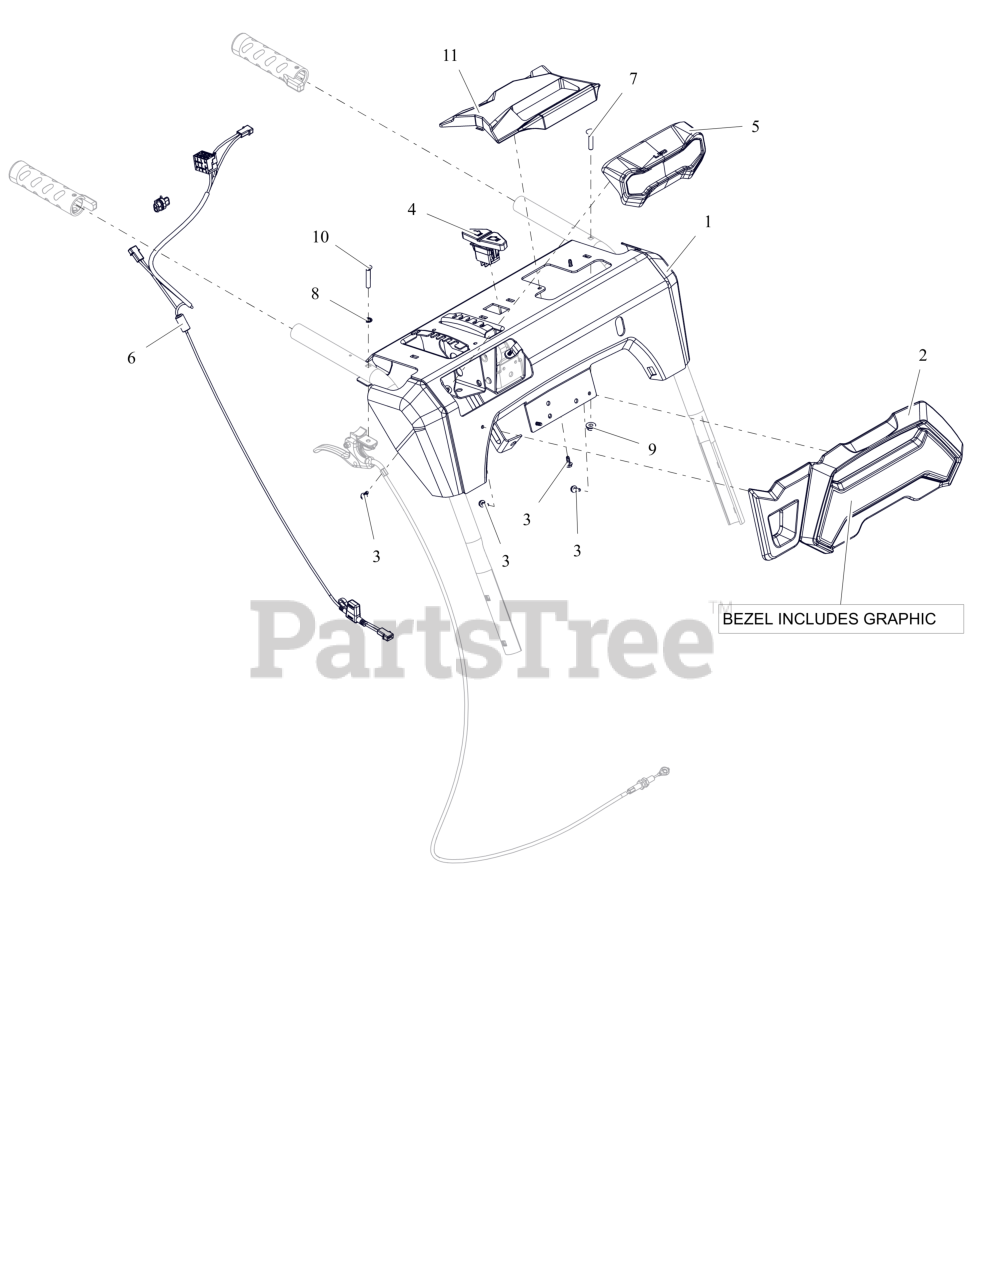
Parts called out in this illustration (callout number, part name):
1	PANEL, CONTROL-EFI ID W/DECAL
2	BEZEL- LARGE - PLATINUM
3	SCR, PLASTIC #10X.50
4	SWITCH- ROCKER SPST-ON/OFF
5	HEADLIGHT ASM- LED
6	HARNESS- WIRE - LT HG
7	BLT-RDHDXLSQNK.25-20X1.25 G5ZC
8	WSHR-LK-INT .250 TH TYA
9	NUT-LK-CTR-FLG .25-20 ZC120
10	SCR,OVAL .25-20X1.50 ZCC
11	BEZEL- OPERATOR - QT
